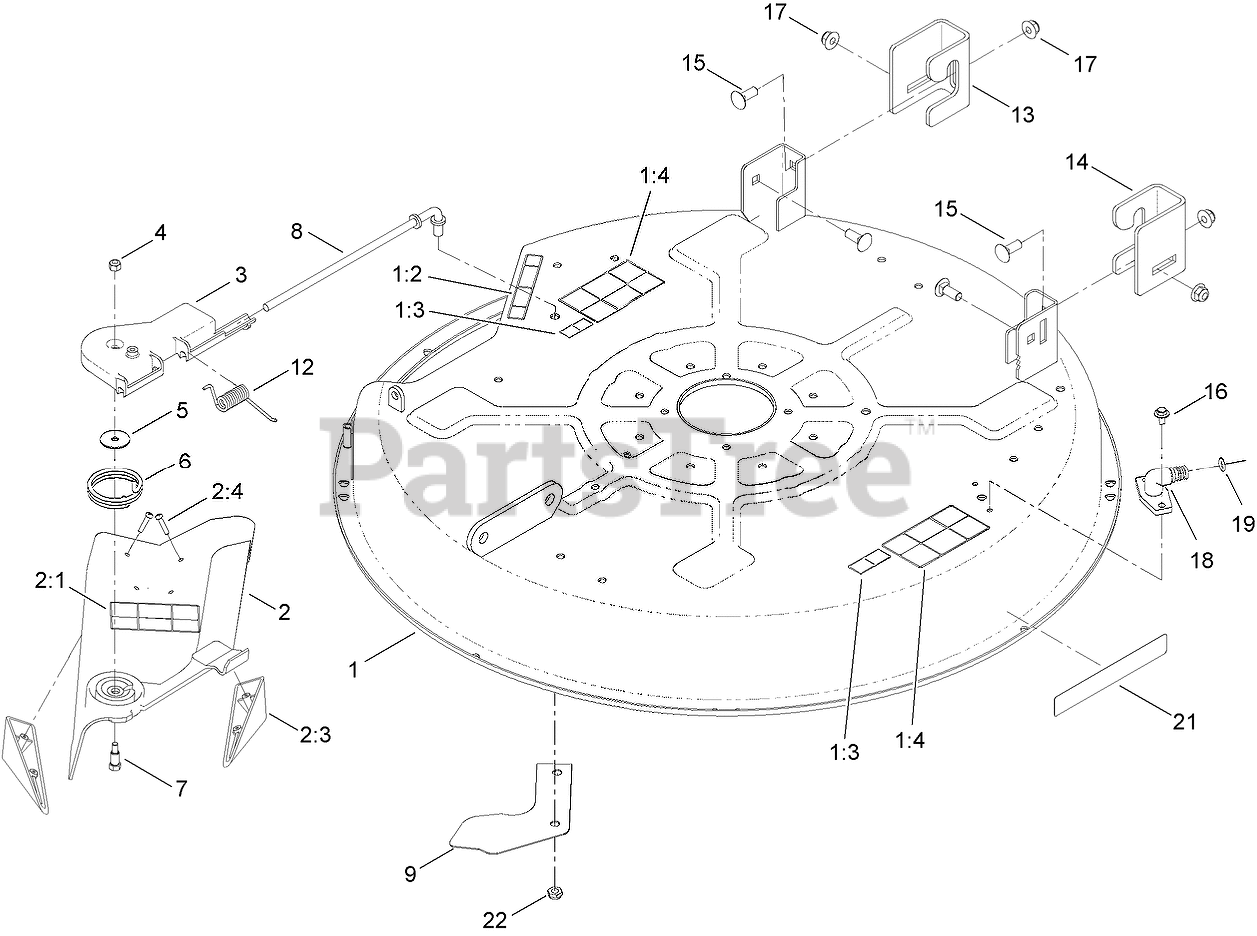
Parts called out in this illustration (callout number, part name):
1	32 INCH DECK AND DECAL ASM
1:2	DECAL-DANGER
1:3	DECAL-DANGER
1:4	DECAL-DANGER
2	32 INCH DEFLECTOR ASM
2:1	DECAL-DANGER
2:3	KICKER
2:4	SCREW-PPH
3	PIVOT-HINGE, DEFLECTOR
4	NUT-LOCK, NI
5	WASHER-FLAT
6	SPRING-TORSION
7	BOLT-SHOULDER
8	ROD-PIVOT
9	RAMP-DEFLECTOR
12	SPRING-TORSION
13	BRACKET-HANGER, RH
14	BRACKET-HANGER, LH
15	BOLT-CARR
16	SCREW-HHFTF
17	NUT-HF, NI
18	FITTING-WASHOUT
19	O-RING
21	DECAL-RECYCLER
22	NUT-LOCK, NI
